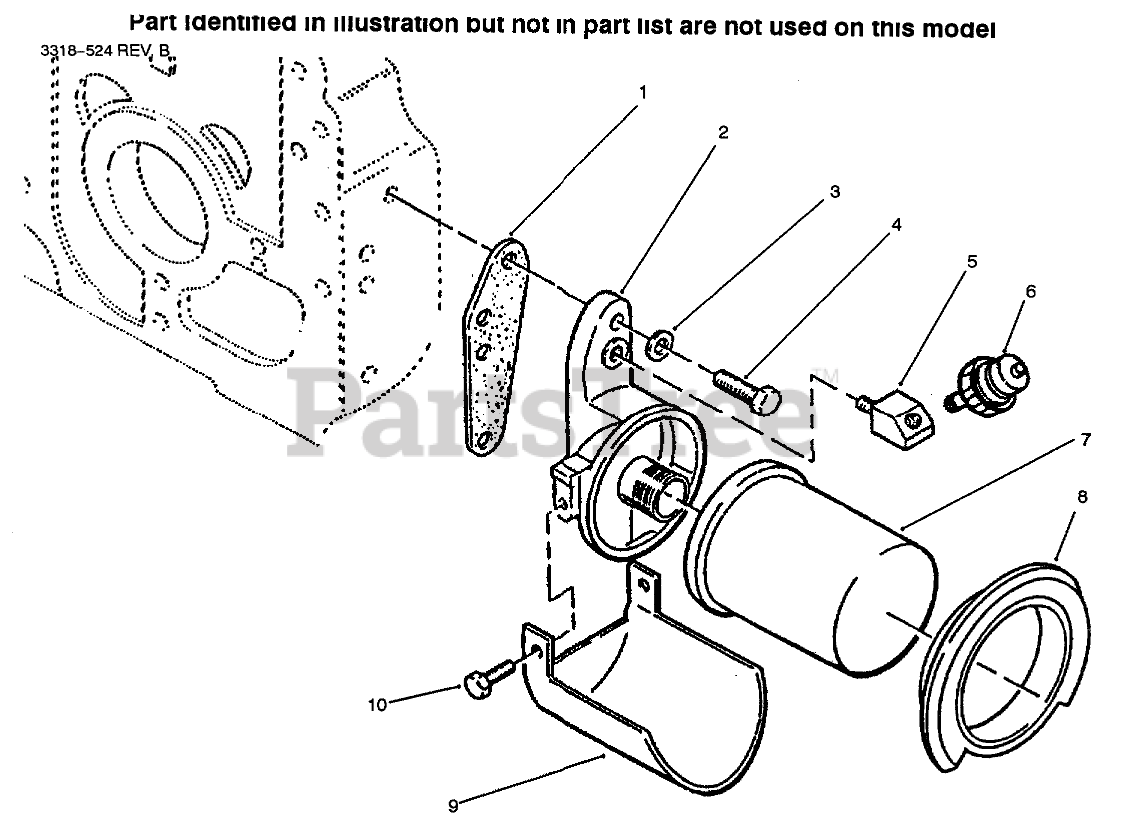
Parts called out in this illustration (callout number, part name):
1	Gasket
2	ADAPTER-OIL FILTER
3	WASHER
4	HHCS 5/16-18 X 1
5	ELBOW-45 DEG
6	SWITCH - OIL PRESSURE
7	OIL FILTER
8	GASKET - AIR SEAL
9	OIL-FILTER DRAIN
10	SCREW-HH
